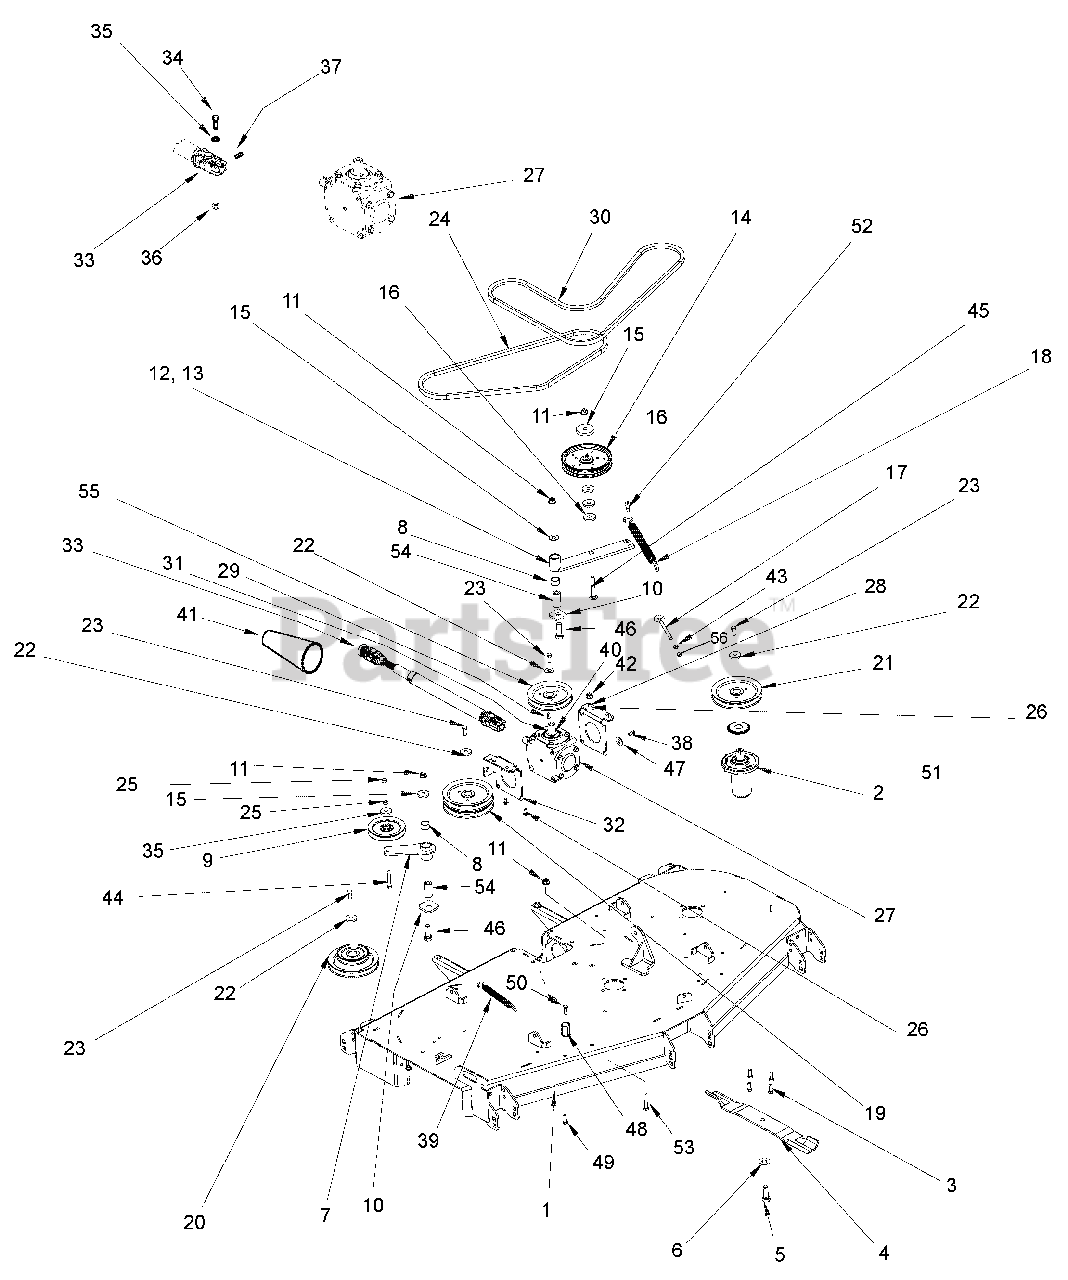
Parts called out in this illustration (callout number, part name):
1	Weldment, 60" Side Discharge Deck (OFM) (890100)
2	Assembly, Spindle
3	Bolt, Hex .38-16 x 1.00 EP30
4	Blade, Mower (20.50") (890100)
5	Bolt-Hex .62-18 x 1.75 Grade 8
6	Washer-Bellville .63 x 1.625 x .14
7	Weldment, Idler Pivot Arm
8	Bushing, 1.00 x 1.125 x 1.937
9	Sheave, .38" ID x 5.00" OD V-Idler
10	Washer, Flat .640 x 1.75 x .250
11	Nut .50-13 Nyloc Flange (890100)
12	Idler Pivot Arm Weldment- Black (890100)
13	Idler Pivot Arm, Rapid XZ 52" (890101)
14	Idler-Flat-Pulley 6.75 x .510 (890100)
15	Washer-Flat-Steel .563 x 1.38 x .109 (890100)
16	Bushing, Spacer .502 x .997 x .50 (890100)
17	Bolt, .38-16 x 5.50 .62 Diameter Eye
18	Spring, Extension (890100)
19	Pulley, Double 1" ID x 6.75" OD (890100)
20	Pulley, Double 1.0" ID x 6.75" x 4.25" OD (890100)
21	Pulley, Single 1" ID x 6.75" OD (890100)
22	Washer, Flat Steel .406 x 1.50 x .245
23	Bolt, Hex .38-16 x 1.00 EP30
24	Belt, B 63.00 Raw Cogged (890100)
25	Nut-Locking-Center .38-16
26	Bolt, Round Head Square Neck .38-16 x 1.00
27	Gear Box- Right Angle 1.05 x 1.0
28	Bracket, Gear Box Mounting
29	Key-Straight .25 x .75 x .25
30	Belt, B 86.00 Wrapped-(100)
31	Washer, Flat Steel 1.00 x 1.505 x .062
32	Bracket, Gear Box Mounting RH
33	Shaft, PTO Drive Assembly
34	Bolt, Hex .38-16 x 1.175 Grade 5
35	Washer, Flat Steel .406 x .812 x .065
36	Nut, Top-Lock Flange .38-16
37	Screw, Set .38-16 x .62
38	Bolt, Hex .38-16 x 1.00 Grade 8 EP30
39	Spring, Extension
40	Ring, External Retaining 1.00 x .078
41	Bellow, PTO Shaft
42	Nut, Nylon Locking Flange .38-16 (890100)
43	Nut, Hex .375-16
44	Bolt, Hex .38-16 x 2.25 Grade 5
45	Bolt, Roundhead Squareneck .50-13 x 3.00 Grade 5 (890100)
46	Bolt, Roundhead Squareneck .50-13 x 3.50 Grade 5
47	Washer, Lock .375 x .115
48	Nut, Coupling .375-16 x 1.75
49	Bolt, Roundhead Squareneck .38-16 x 1.00 Grade 5
50	Bolt, Hex .38-16 x 1.50
51	Retainer, Grease
52	Bolt, Shoulder Hex .38-16 x .30
53	Bolt, Roundhead Squareneck .50-13 x 1.50
54	Bushing, Spacer, .505/.500 x .999/.996 x 2.05/2.03
55	Pulley-V 1.00 ID x 6.75 OD
56	Nut, Locking Center Jam .375-16
